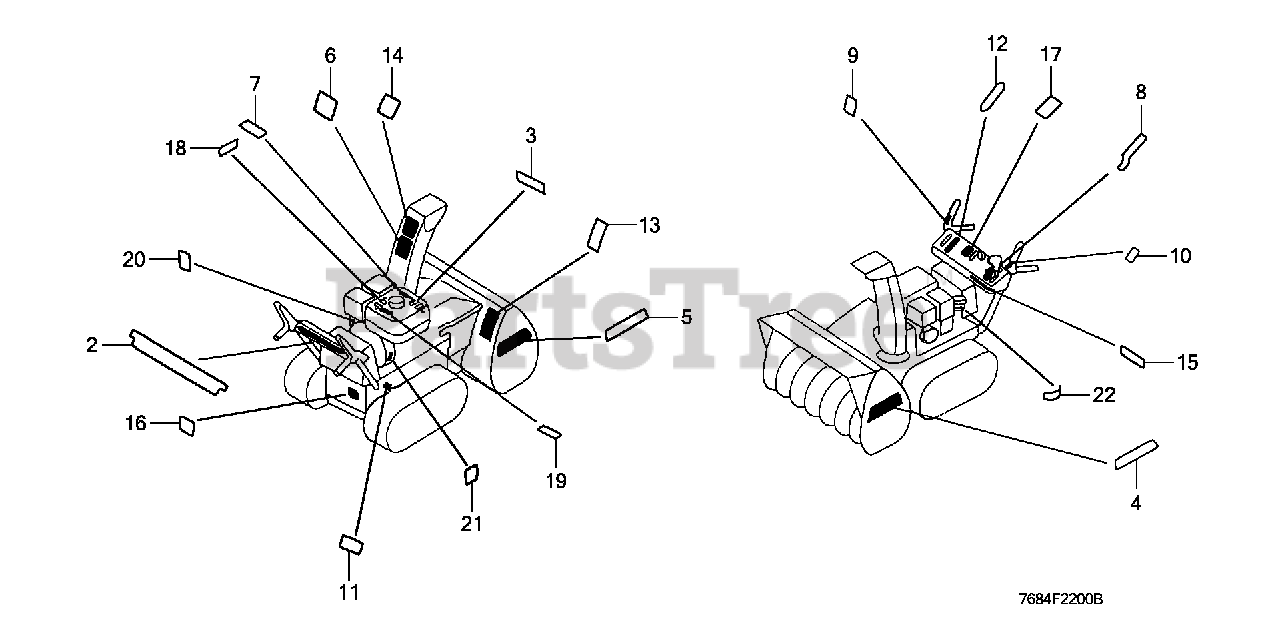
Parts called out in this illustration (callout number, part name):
2	LABEL, OPERATION (ENGLISH)
2	LABEL, OPERATION (C)(ENGLISH)
3	MARK, HONDA EMBLEM
4	MARK, L. STRIPE (HS828)
5	MARK, R. STRIPE (HS828)
6	LABEL, WARNING (ENGLISH)
7	LABEL, WARNING FUEL (ENGLISH)
8	MARK, CHANGE INDICATION
9	MARK, AUGER CLUTCH (ENGLISH)
10	MARK, CLUTCH (ENGLISH)
12	MARK, CHUTE CONTROL OPERATION (ENGLISH)
13	MARK, HOUSING DANGER (ENGLISH)
14	MARK, DISCHARGE DANGER (ENGLISH)
15	MARK (H.S.T.)
16	MARK, INDICATION (H.S.T.)(ENGLISH)
17	MARK, THROTTLE (ENGLISH)
18	MARK, EX. CAUTION (ENGLISH)
19	MARK, FUEL INDICATION (PICTOGRAPH)
20	MARK, FUEL INDICATION (ENGLISH)
21	MARK, OIL CAUTION (ENGLISH)
22	LABEL, OIL RECOMMENDATION (ENGLISH)
